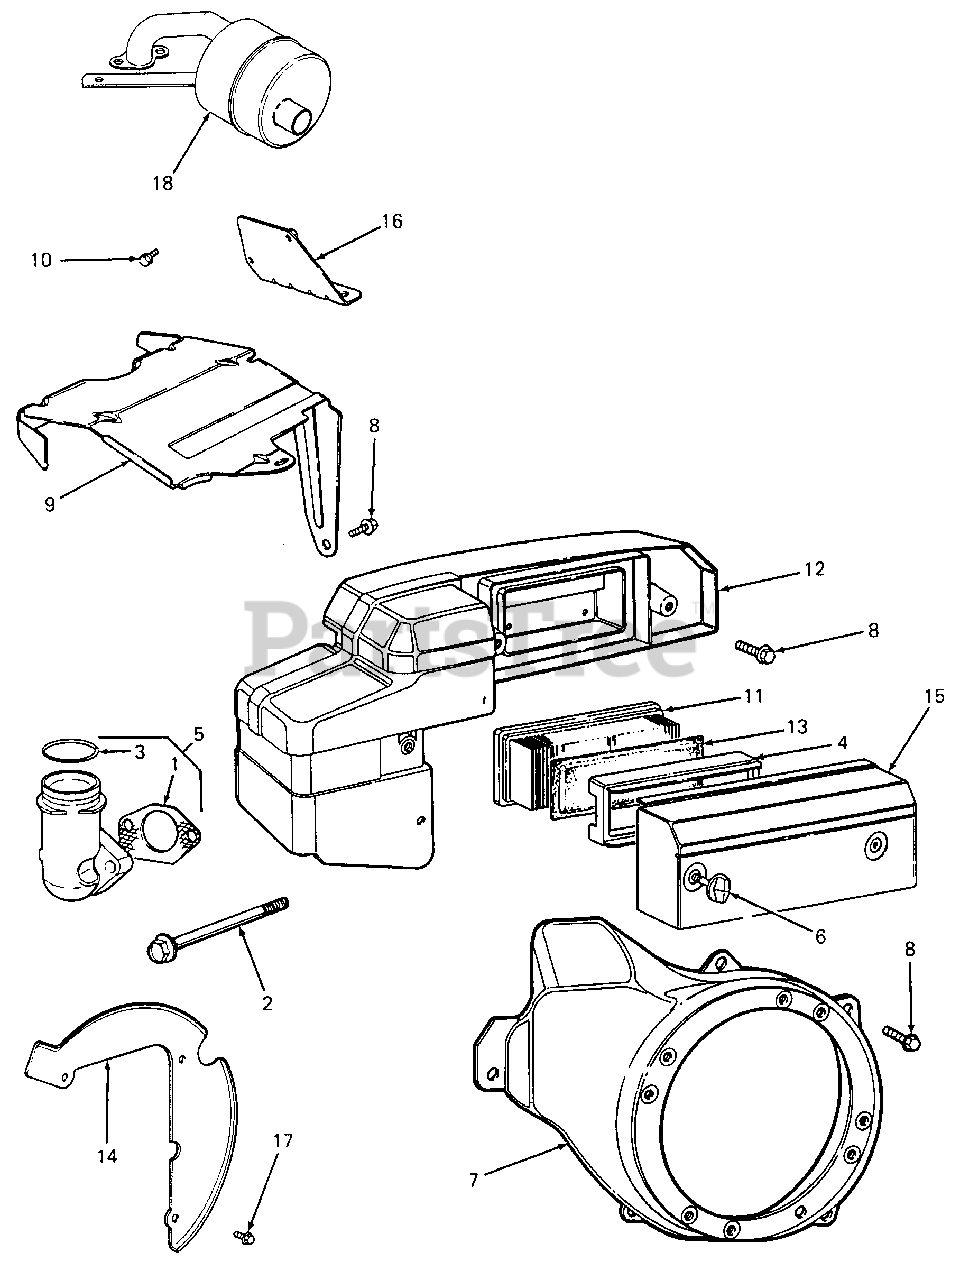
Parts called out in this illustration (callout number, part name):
1	Gasket, Elbow
2	Screw, Mounting
5	Pipe Assy, Air Cleaner
6	Stud Assy, Air Cleaner
7	Housing, Blower
8	Screw, Sems
9	Shield, Cylinder
10	Screw, Bracket
11	Cartridge, Air Cleaner
13	Element, Air Cleaner
14	Plate, Back
15	Cover, Air Cleaner
16	Bracket, Fuel Pump
17	Screw, Hex Hd
18	Muffler Assy
